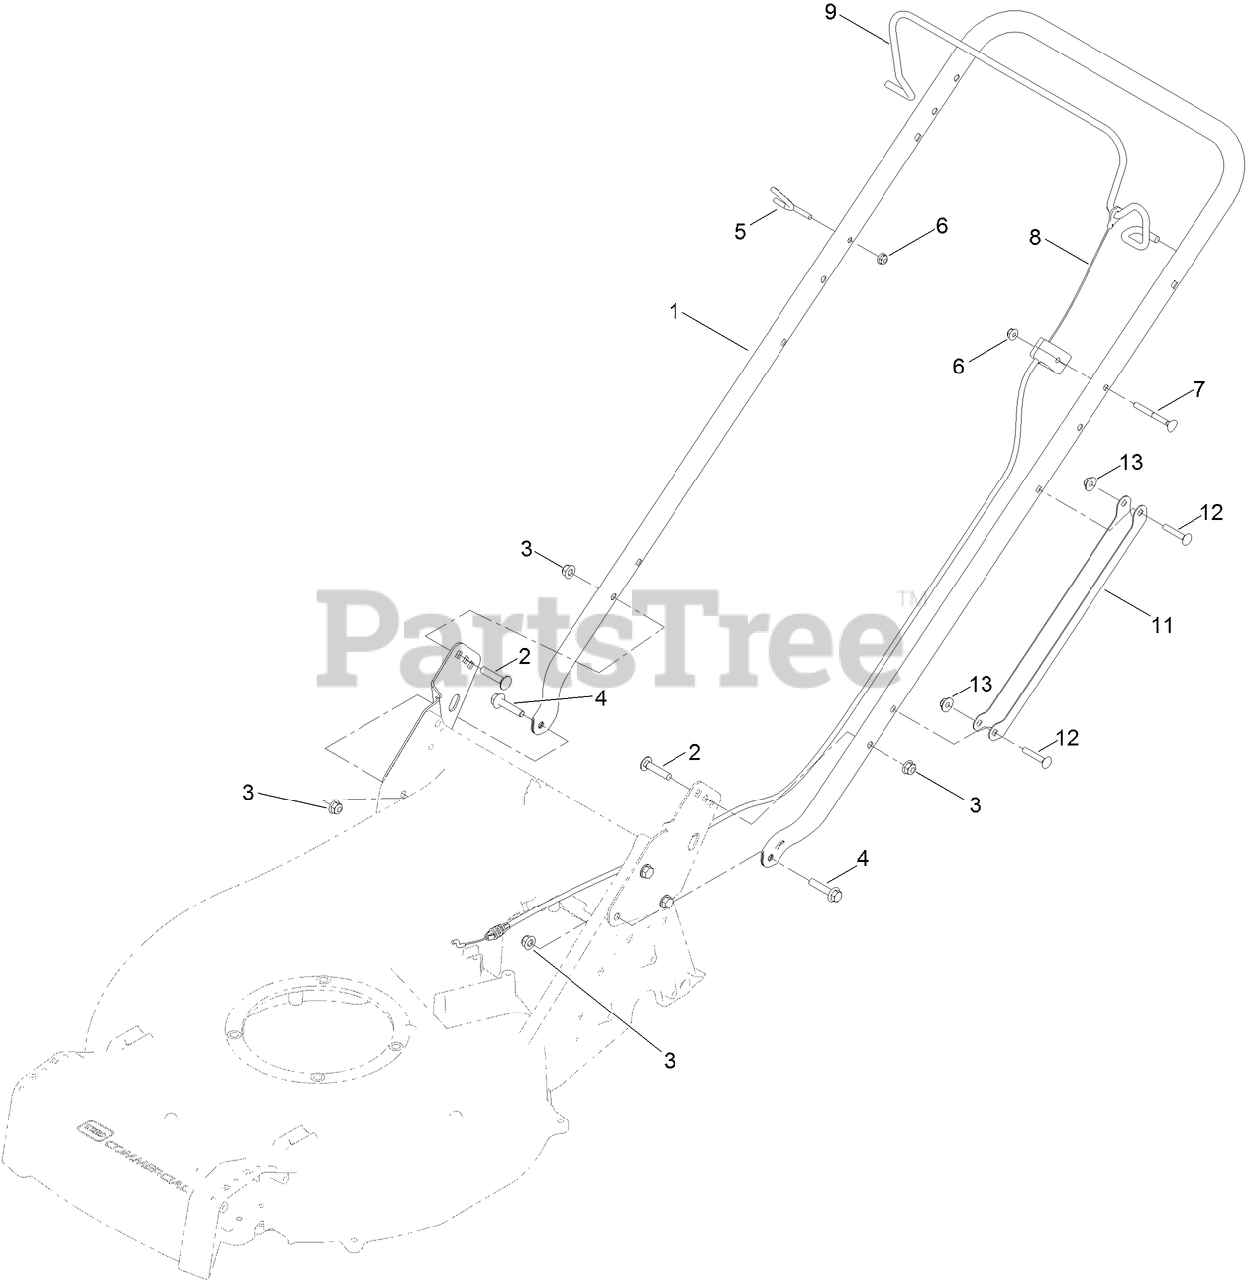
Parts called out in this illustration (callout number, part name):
2	BOLT-CARR
3	NUT-HF, NI
4	SCREW-HHF
5	GUIDE-ROPE
6	NUT-HF
7	SCREW-HANDLE
8	CABLE-BRAKE
9	BAIL-BRAKE
11	GUARD-CABLE, HANDLE
12	SCREW-CARR
13	NUT-HF
